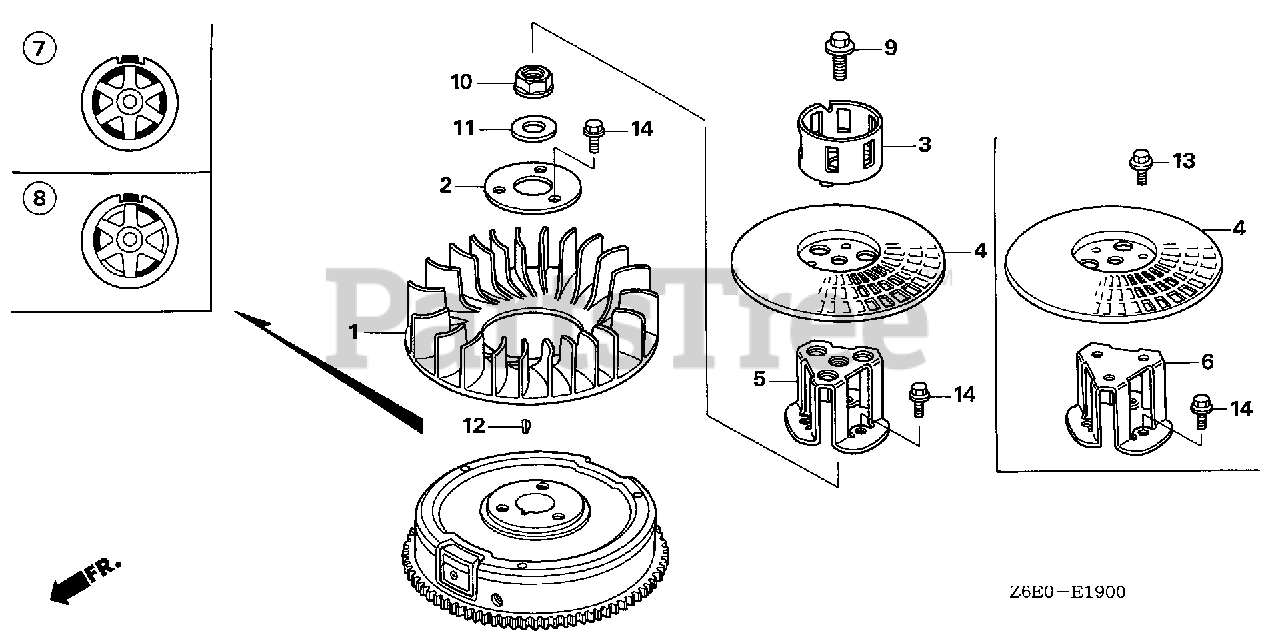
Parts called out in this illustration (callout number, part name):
1	FAN, COOLING
3	PULLEY, STARTER
4	GRID, SCREEN
5	SPACER, STARTER PULLEY MOUNTING
9	BOLT, UBS (12X28)
10	NUT, FLANGE (20MM)
11	WASHER (20MM)
12	KEY, SPECIAL WOODRUFF (25X18)
14	BOLT, FLANGE (8X16)
